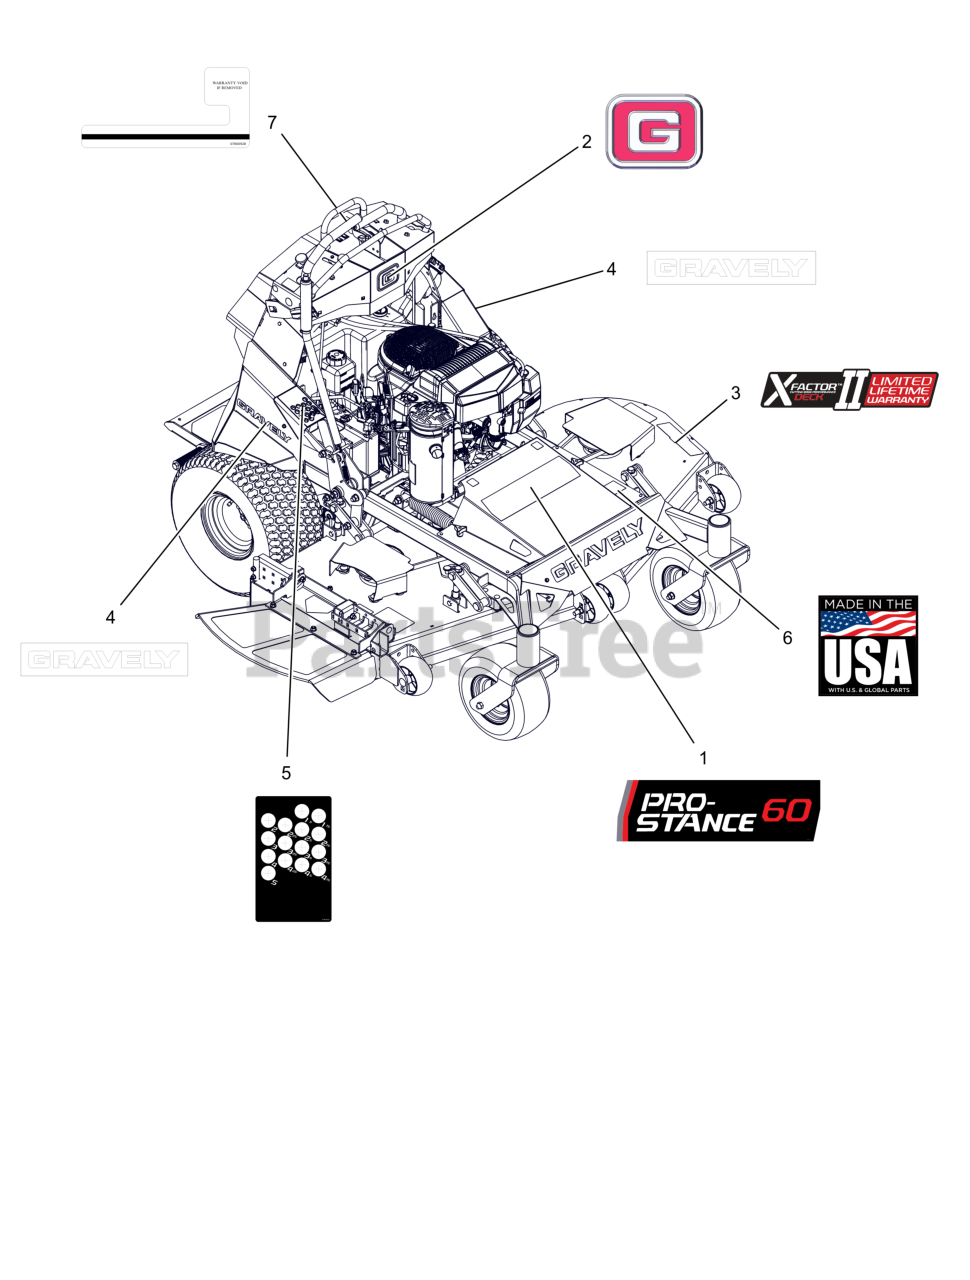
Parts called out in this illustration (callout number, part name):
1	DECAL, PROSTANCE 60
2	DECAL, GRAVELY BRAND
3	DECAL, X-FACTOR DECK
4	DECAL, 9.5" GRAVELY LOGO
5	DECAL, DECK - HEIGHT ADJUST
6	DECAL, MADE IN USA
7	DECAL,HOURMETER - SECURITY
